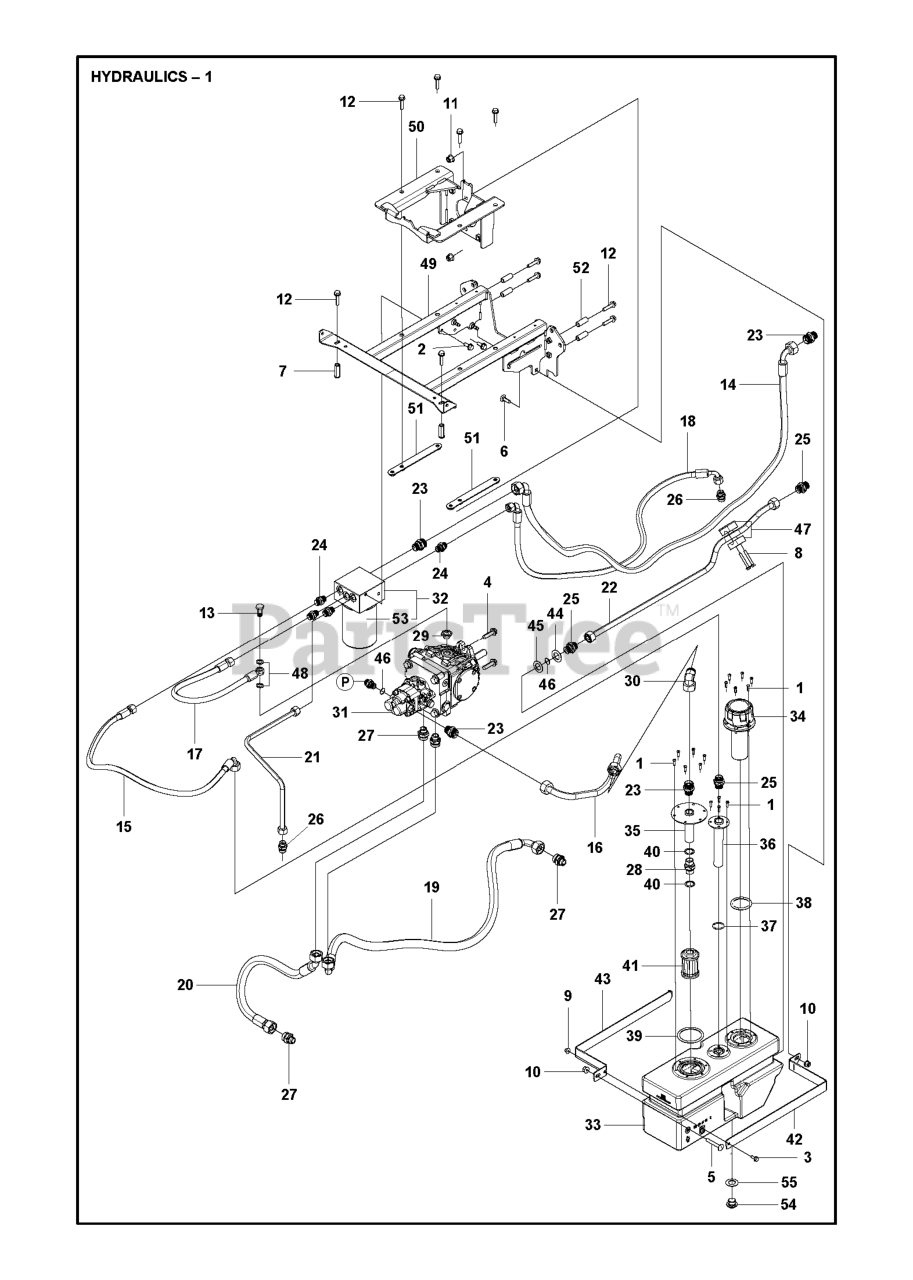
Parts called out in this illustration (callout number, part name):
1	NUT
2	SHIELD
3	STAKE PIN TI
4	KLIP RING TI
5	RP BOLT 5/16-18 X3/4 ZN/YEL GR
7	BRACKET.LATCH.STAKE.3.20.BLACK
8	SPRING CRT
9	SHIELD
12	WASHER.LOCK.HVY.HLCL.SPR.5/16
13	BOLT.CARRIAGE.5/16-18
14	BRACKET.TINE.SHIELD.TILLER.BLA
15	SIDE SHIELD RH
16	NUT
20	NUT.HEX.3/8-16UNC
21	STAKE.DEPTH.16.CRT.BLACK
22	BOLT.375-16
25	VINYL CAP TI
26	PAD IDLER TI
27	SHIELD LEVELING
28	PIN.HINGE.TILLER
29	SIDE SHIELD
30	LOCKNUT-FLANGE 5/16-18
